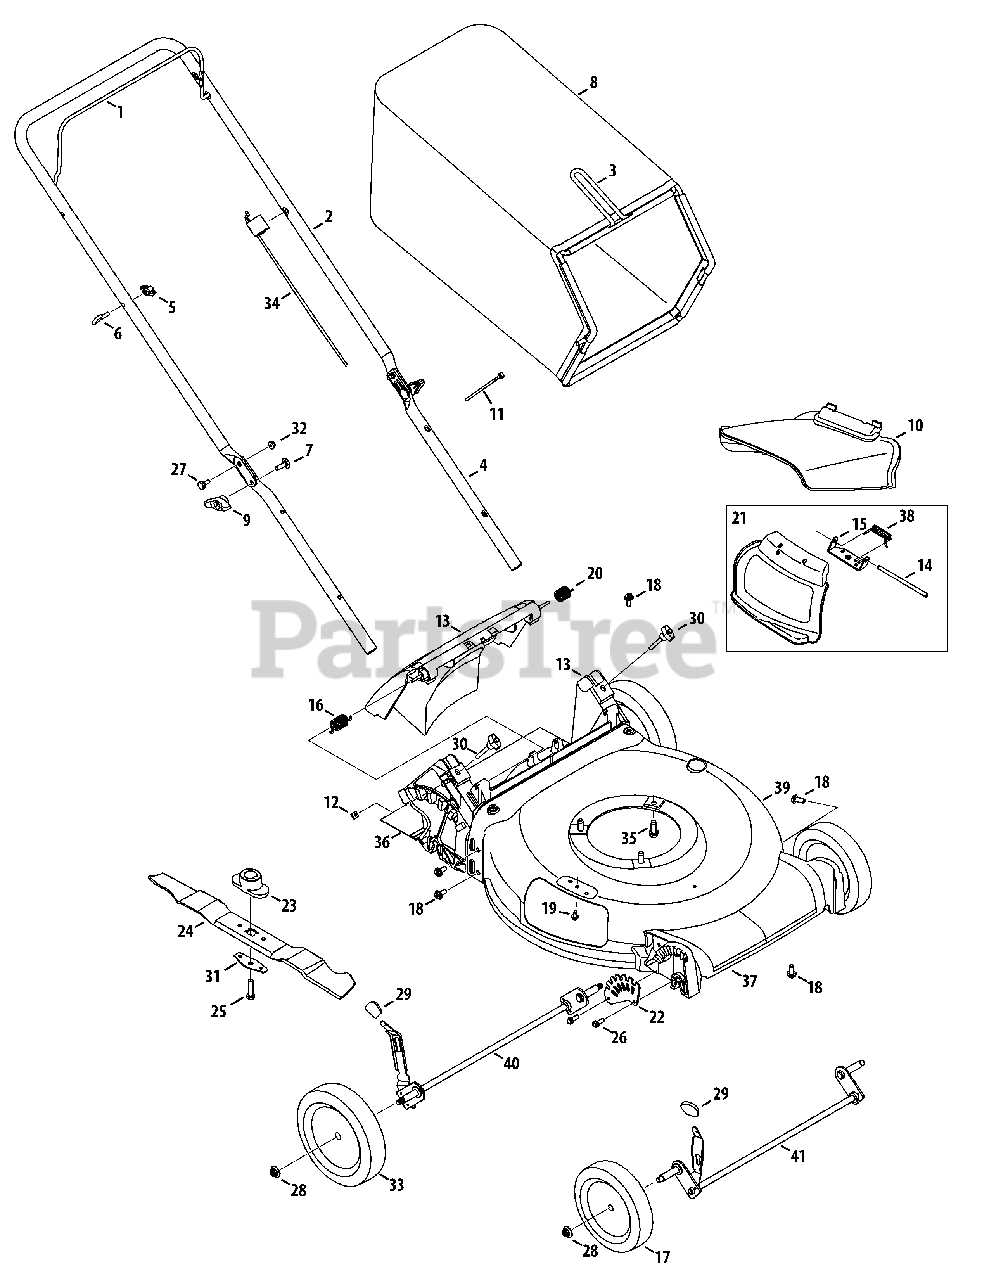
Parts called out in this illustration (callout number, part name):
1	Blade Control
2	Upper Handle, Non-Adjustable
3	Grass Catcher Frame
4	Lower Handle
5	Wing Nut
6	Rope Guide
7	Carriage Screw ,5/16-18
8	Grass Bag
9	Wing Knob, Black
10	Side Chute
11	Cable Tie
12	Nut, Sq., 1/4-20
13	Rear Discharge Door Assembly
14	Hinge Pin
15	Chute Deflector Bracket
16	Torsion Spring - RH
17	Front Wheel Gray
18	Screw, 5/16-14 x .750
19	Screw, 1/4-20 x .500
20	Torsion Spring - LH
21	Hinged Mulch Plug Assembly
22	Front Height Adjuster Plate
23	Blade Adapter
24	Mulching Blade
25	Screw , 3/8-24 x 1.50
26	Screw, 1/4-15 x .750
27	Sldr. Screw, .375 x .126 x 1/4-20
28	Flange Lock Nut, 3/8-16
29	Adjustment Lever Knob, Red
30	Wing Nut
31	Blade Bell Support
32	Nut, Flange Lock, 1/4-20
33	Rear Wheel Gray
34	Control Cable, 37.58"
35	TT Sems Screw, 3/8-16 x 1.0
36	Trail shield
37	Front Cover
38	Torsion Spring
39	Deck , 21" - Universal Red
40	Rear Axle Assembly
41	Front Axle Assembly
